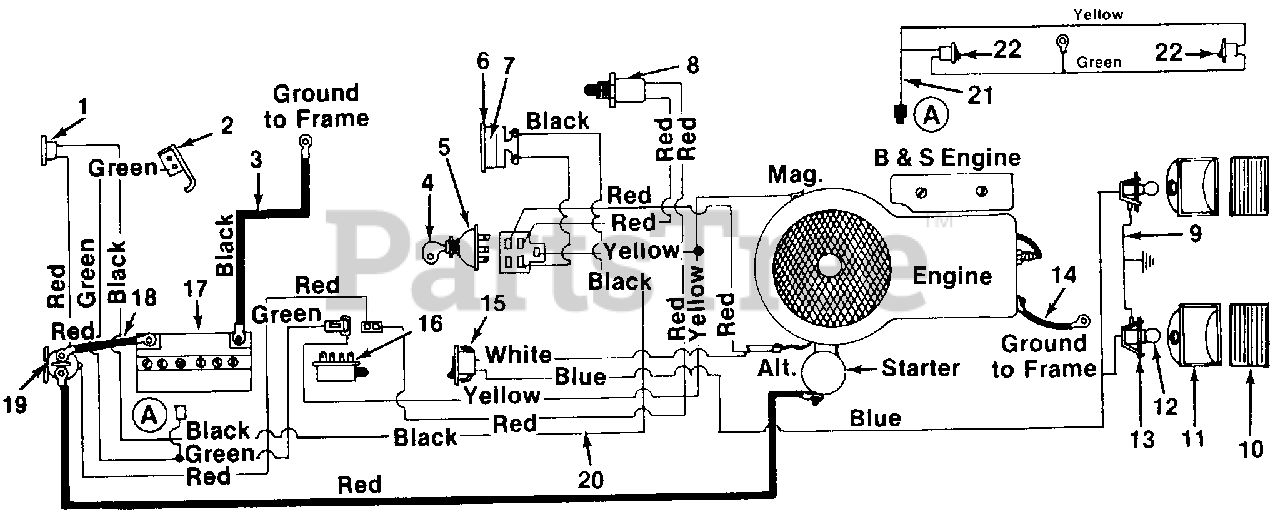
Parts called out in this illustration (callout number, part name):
1	Circuit Breaker
2	Spring-Switch-Reverse
3	Ground Wire 9.0" Lg.
4	Ignition Key
5	Ignition Switch
6	Ammeter
7	Foam Strip
8	Safety Switch
9	Ground Wire
10	Lens
11	Headlight Housing
12	Lamp
13	Socket
14	Ground Wire 7.25" Lg.
15	Light Switch
16	Safety Switch
17	Battery
18	Electric Wire w/Boot
19	Solenoid
20	Wire Harness
21	Wire Lead
22	Safety Switch
